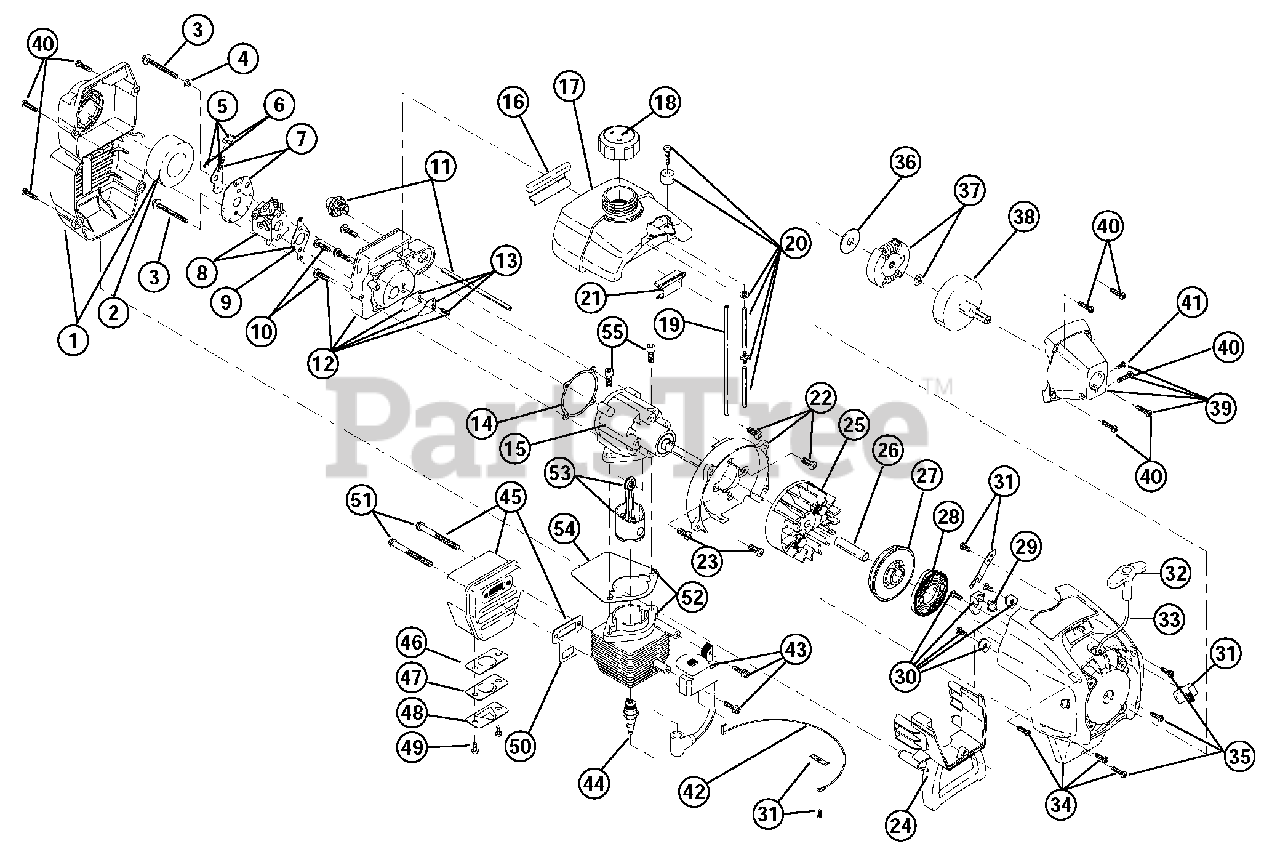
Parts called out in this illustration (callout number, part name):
1	Air Cleaner/Muffler Cover Assembly
2	Air Cleaner Filter
3	Carburetor Mounting Screw Assembly
4	Wavey Washer
5	Choke Lever Assembly
6	Choke Knob and Screw
7	Choke Lever and Plate
8	Carburetor Assembly
9	Carburetor Gasket
10	Carb Mount Screw
11	Primer and Hose Assembly
12	Carb Mount Assembly
13	Reed Assembly
14	Carburetor Mount Gasket
15	Crank Case Service Assembly
16	Rear Mounting Pad
17	Fuel Tank Assembly
18	Fuel Cap Assembly
19	Fuel Return Line
20	Fuel Line Assembly
21	Front Mounting Pad
22	Shroud Assembly
23	Shroud Screw
24	Shroud Extension and Stand
25	Flywheel Assembly
27	Recoil Pulley Assembly
28	Recoil Spring
29	Rope Guide
30	Pulley Retainer Assembly
31	Switch Assembly
32	Pull Handle
34	Starter Housing Assembly
35	Housing Screw
36	Clutch Washer
37	Clutch Rotor Assembly
38	Clutch Drum Assembly
39	Clutch Cover Assembly
40	Cover Screw
41	Anti-Rotation Screw
42	Wire Lead
43	Module Assembly
44	Spark Plug
45	Muffler Assembly
46	Spark Arrestor Screen
47	Spark Arrestor Plate
48	Spark Arrestor Hood
49	Spark Arrestor Screw
50	Exhaust Gasket
51	Muffler Mounting Bolt Assembly
52	Cylinder Assembly
53	Piston and Rod Assembly
54	Cylinder Gasket
55	Cylinder Bolt
